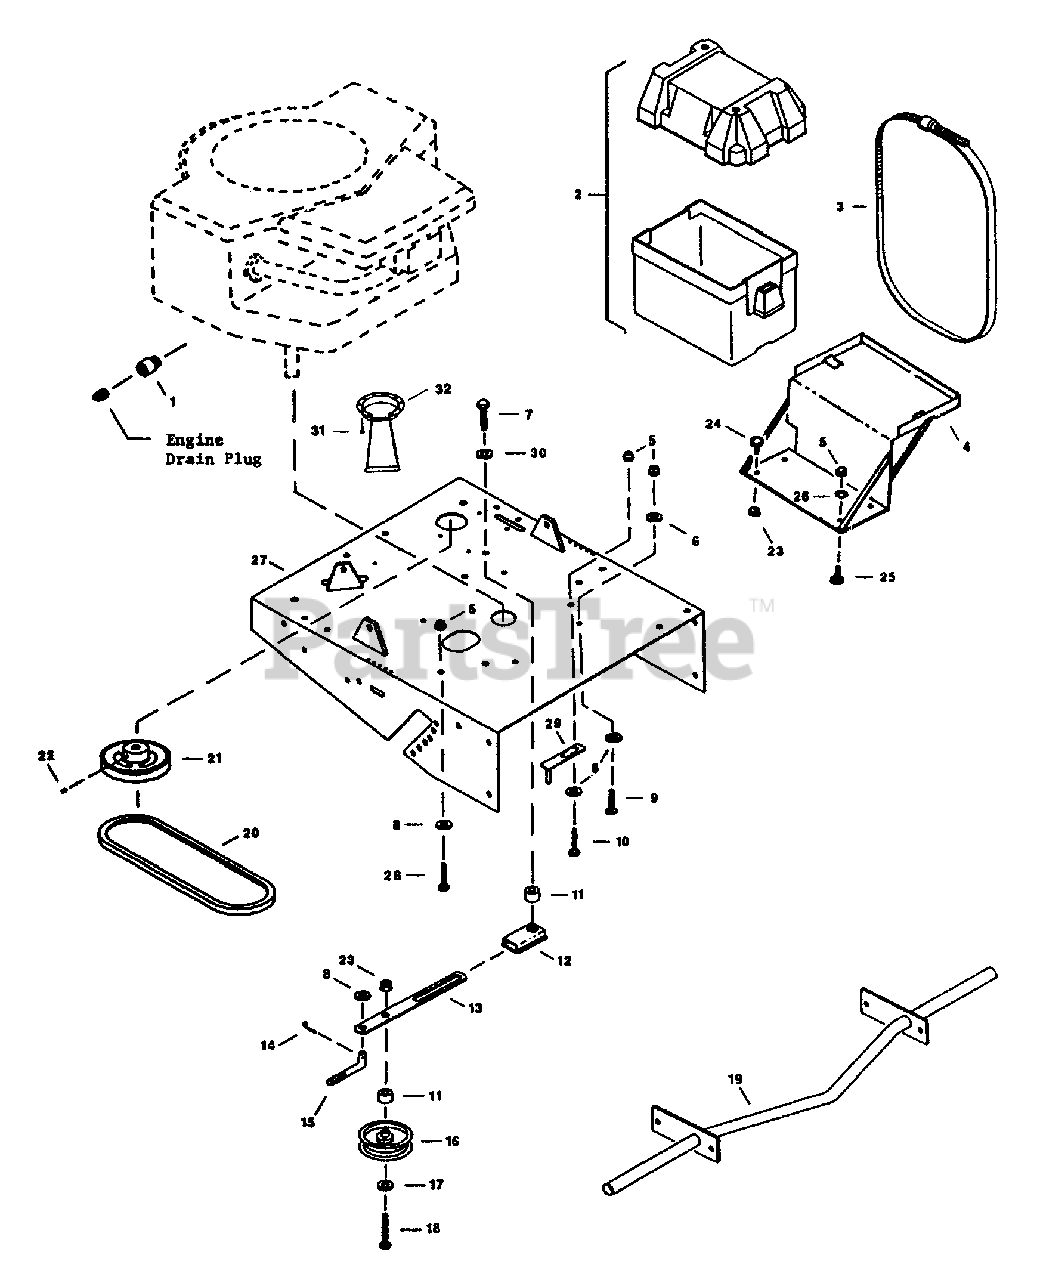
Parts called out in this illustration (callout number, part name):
1	Oil Drain Extension
2	Battery Case
3	Hose Clamp
4	Battery Stand
5	5/16"-18 Nyloc Hex Nut
6	5/16" Lock Washer
7	3/8"-16x1-3/4" Hex Hd. Cap Screw-Grade 5
8	5/16" Std. Flat Washer
9	5/16"-18x1-1/2" Hex Hd. Cap Screw-Grade 5
10	5/16"-18x3/4" Hex Hd. Cap Screw
11	Spacer
12	Bracket Slide
13	Slide Bar
14	3/32" x 1/2" Cotter Pin
15	Variable Adjustment Rod
16	Idler Pulley
17	3/8" Std. Flat Washer
18	3/8"-16x2-1/2" Hex Hd. Cap Screw-Grade 5
20	Belt
21	Transmission Pulley
22	5/16"-18x3/8" Nyloc Knurled Cup Point Set Screw
23	3/8"-16 Nyloc Hex Nut
24	3/8"-16x1" Hex Hd. Cap Screw-Grade 5
25	5/16"-18x1" Hex Hd. Cap Screw
26	5/16" External Tooth Lock Washer
27	Rear Deck
28	5/16"-18x1-1/4" Hex Hd. Tap Bolt
29	Belt Guide
30	3/8" Lock Washer
32	Muffler Deflector
